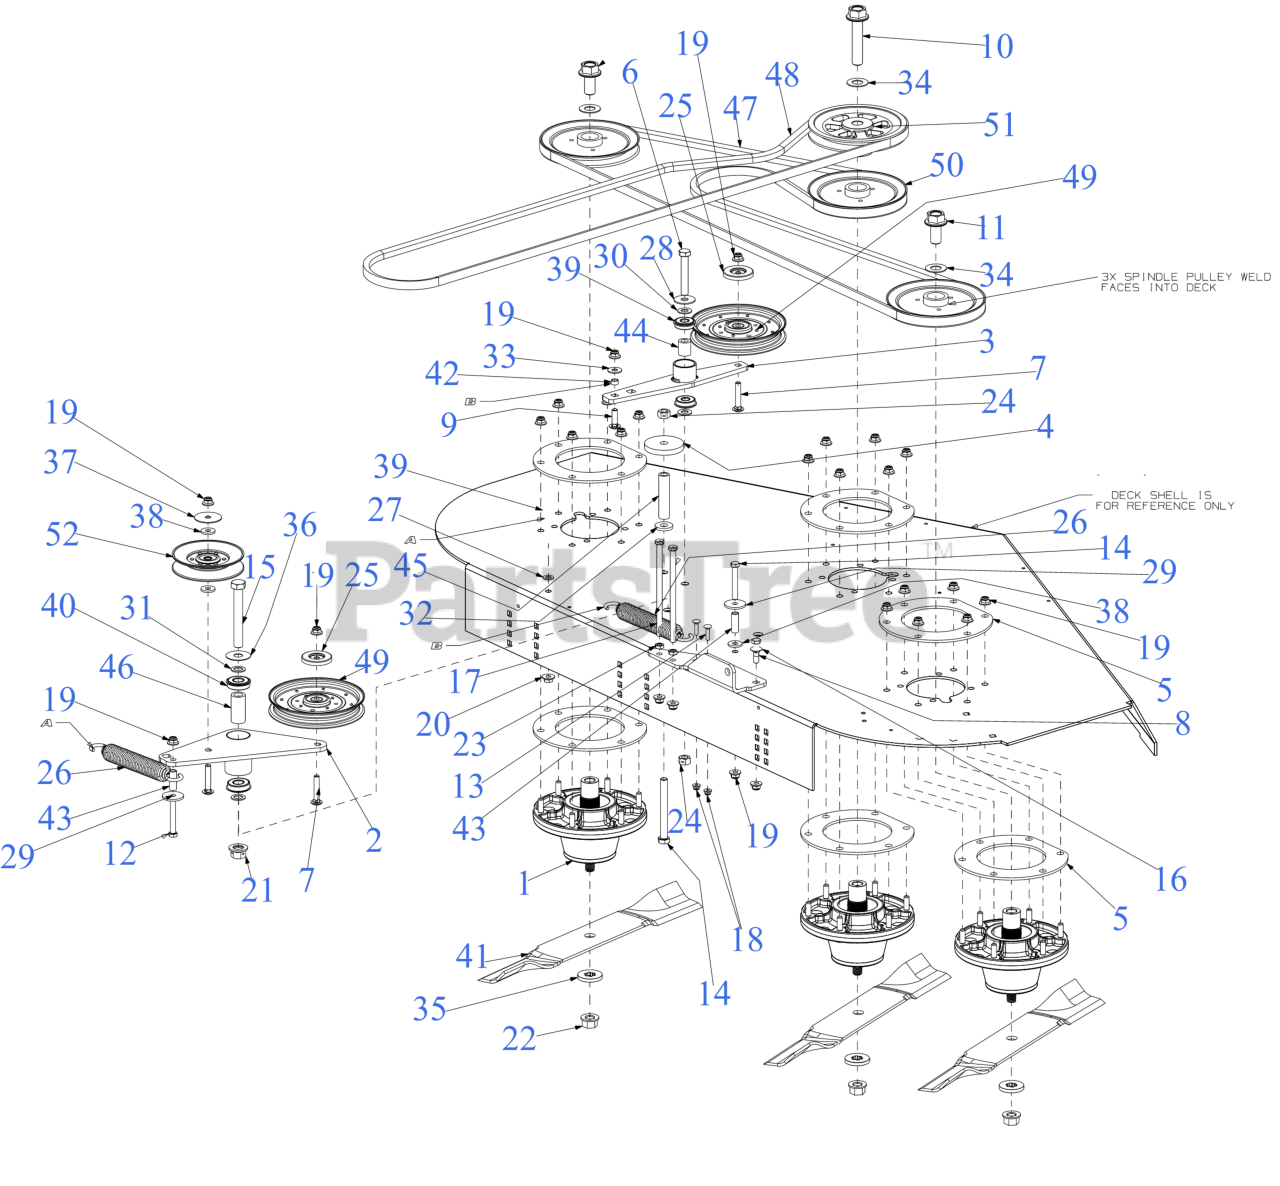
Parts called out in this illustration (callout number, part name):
1	SPINDLE ASSEMBLY
3	IDLER BRACKET
4	SPACER PLATE
5	SPINDLE SUPPORT BRACKET TOP/BTM
6	SCREW-HEX 1/2-13 x 3.00
7	CARRIAGE BOLT 3/8-16 x 2
8	SCREW 3/8-16 x 1 GR5
9	CARRIAGE BOLT 3/8-16 X1.25 GR5
10	CAP SCREW-HHFLG 3/4-10 X 3.50 GR8
11	CAP SCREW-HHFLG 3/4-10 X 1.50 GR8
12	HEX SCREW-3/8-16X2.5 GR5
13	SCREW 1/4-20 x 1 GR5
14	SCREW 1/2-13 x 4.5 GR 5
15	SCREW 5/8-18X4.5 GR5
16	CARRIAGE BOLT 3/8-16 x 1.00 GR5
17	SCREW 3/8-16 x 7.00 GR5
18	FLANGE LOCK NUT
20	FLANGE LOCK NUT
22	FLANGE NUT - 5/8-18 GDE 8
23	HEX JAM NUT 3/8-16 GR5
24	HEX NUT CTR LK 1/2-13
25	PULLEY CAP
26	SPRING 1.25" DIA x 8.5" LONG
27	FLAT WASHER
28	WASHER .51 x 1.5 x .07
29	FLAT WASHER .390x1.500x.134
30	FLAT WASHER .510 x .995
31	FLAT WASHER
32	FLAT WASHER .531 x 1.25 x .181
33	WASHER-.395 x 1.0 x .62
34	FLAT WASHER
35	FLAT WASHER - SPECIAL
36	THRUST WASHER .635x1.750x0.055
37	HUB CAP WASHER .406 x 1.92 x .060
38	FLAT WASHER .406ID X1.0 OD
39	ROLLER BEARING .5X1.37X.44
40	BALL BEARING W/RET
41	21" BLADE (HI LIFT)
41	Cub Cadet 60" BLADE SET
41	Genuine Factory Parts 60" BLADE SET
41	LOW-LIFT 21"BLADE (60"DECK)
41	BLADE- HI LIFT 21.0 XTREME
41	21" XTREME BLADE
44	SPACER 0.51 x 0.88 x 1.00
46	SPACER 0.63 x 1.00 x 2.01
48	V-BELT B SEC x 105.15
49	IDLER PULLEY
50	SPINDLE PULLEY 7"
51	PULLEY-7.01 OD x .75 ID
52	IDLER PULLEY 5.06 OD
